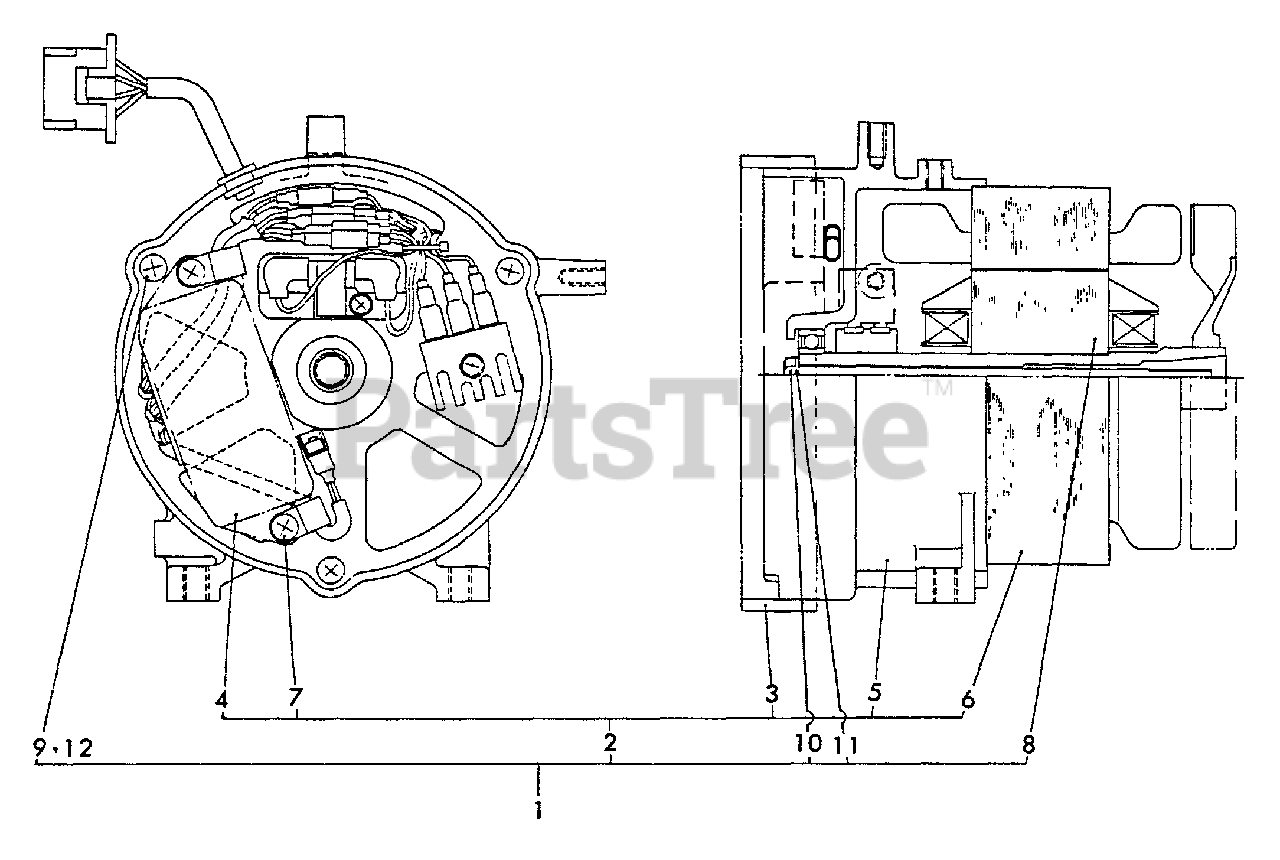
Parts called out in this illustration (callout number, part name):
1	GENERATOR
2	STATOR ASSY
3	URATHANE FOAM
4	CONDENSER
5	COVER - REAR
6	STATOR
7	SCREW - 4X10
8	ROTOR ASSY
9	BOLT
10	BOLT
11	LOCKWASHER
12	LOCKWASHER - 5
